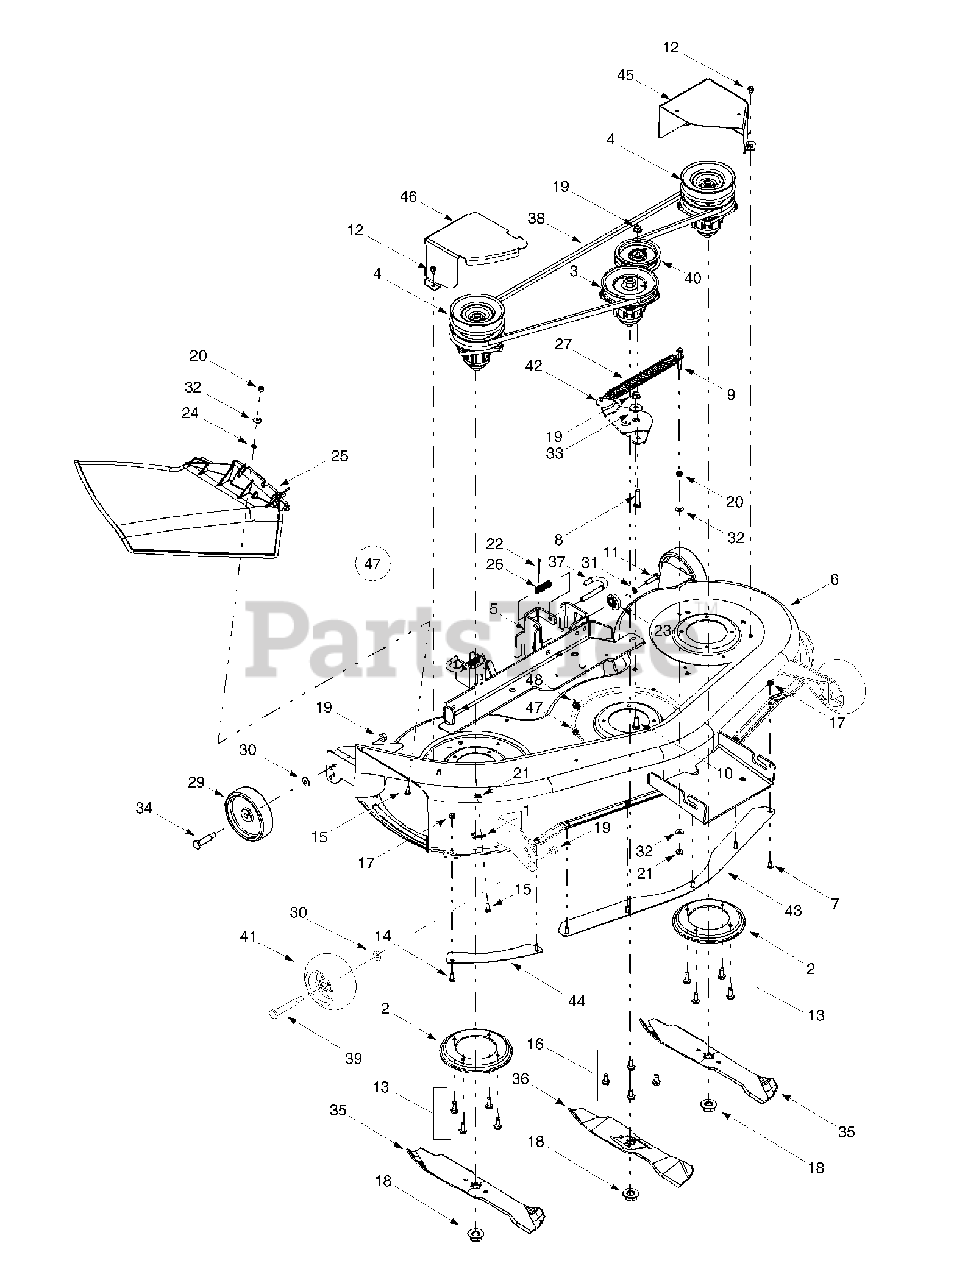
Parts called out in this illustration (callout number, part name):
1	Retainer Hook
4	Double Pulley Spindle Assembly
8	Hex Cap Screw, 3/8-16 x 1.5
9	Hex Cap Screw, 1/4-20 x 2.0
10	Hex Cap Screw, 3/8-16 x 1.0
11	Hex Cap Screw, 5/8-18 x 1.25
12	Self-tapping Screw,1/4-20 x .5
13	Self-tapping Screw,15/16-18 x .875
14	Hex Screw, 1/4-20 x .75
15	Hex Cap Screw, 1/4-20 x .62
16	Self-tapping Screw, 5/16-18 x .75
17	Hex Sems Nut, 1/4-20
18	Hex Flange Nut, 5/8-18
19	Flange Lock Nut, 3/8-16
20	Hex Nut, 1/4-20
21	Hex Flange Lock Nut, 1/4-20
22	Cotter Pin, 1/8 x 1.25
23	Deck Adjustment Gear
24	Push Nut. .25 x .5
25	Side Discharge Chute Assembly
26	Compression Spring, .406 x .531 x 1.75
27	Extension Spring, .91 x 7.3
29	Deck Wheel, 5 x 1.38
30	Bell Washer, .401 x .87 x .063
31	Lock Washer, 5/16
32	Bell Washer, .265 x .75 x .062
33	Shoulder Spacer, .625 x 1.16
34	Shoulder Screw
35	Three-in-one Blade, Star Center, 16.28"
36	Three-in-one Blade, Star Center, 14.88"
37	Deck Release Pin
38	Deck Belt, Poly
39	Shoulder Screw, 1/2-2.5
40	Idler Pulley, 3.5
41	Deck Wheel, 5.0
